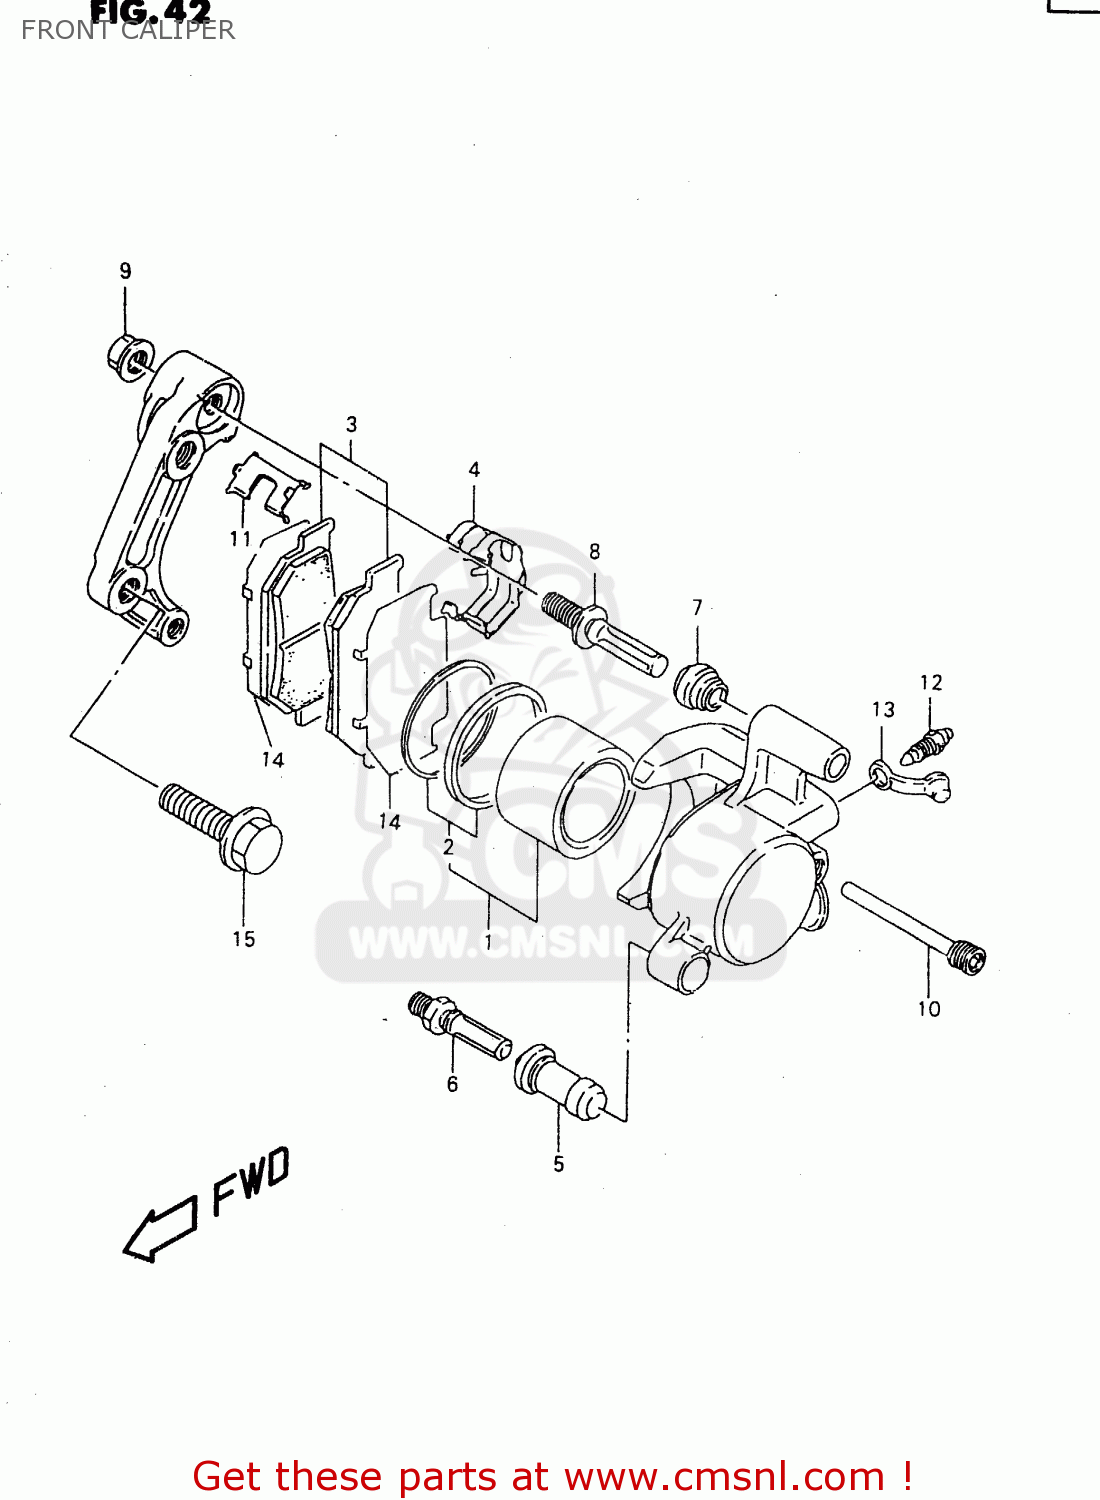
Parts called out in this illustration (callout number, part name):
1	PISTON SET
2	SEAL SET,PISTON
3	PAD SET (NAS)
4	SPRING
5	BOOT
6	BOLT
7	BOOT
8	PIN,SLIDE
9	NUT,SLIDE PIN
10	PIN,HANGER
11	RETAINER
12	BLEEDER
13	CAP,BLEEDER
14	SHIM
15	BOLT
